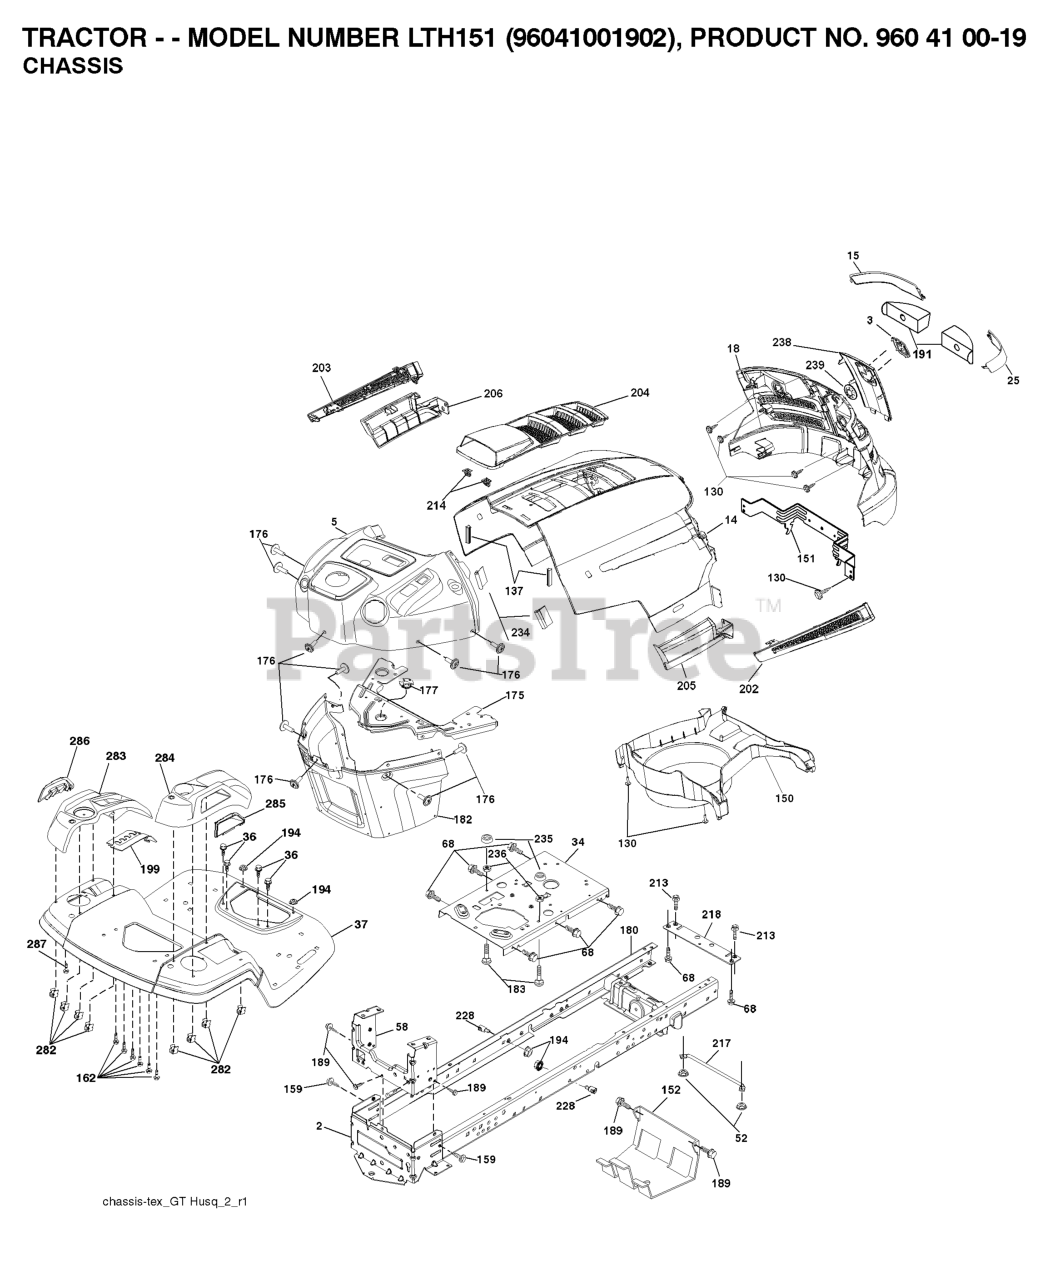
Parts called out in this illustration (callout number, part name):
2	DRAWBAR.LOWER.2PC.18/22
3	RP LOGO
5	DASH
14	HOOD
15	LENS.HUSQVARNA LT.LH
18	RP GRILLE/LENS ASM.
25	LENS.HUSQVARNA LT.RH
34	PLATE.ENGINE.WELDED.CHASSIS
36	SCREW 5/16"
37	RP FENDER.TLT.FS.W/CPH.422
52	LOCKNUT
58	DRAWBAR UPPER 2PC SMALL FENDER
68	Screw 5/16-18 x 1/2 Hex, Self Tapping 5/16-18 x 1/2
130	SCREW
137	BUMPER DASH
151	BRACKET PIVOT
152	SHIELD.BROWNING.W/TEX
159	SCREW, 3/8-16X3/4
162	SCREW.HI-LO.CONSOLE
175	CROSSMEMBER
176	SCREW.#10-24X5/8.RN.QU
177	BUSHING STEERING
180	CHASS.WLDMNT.TL.12GA/2P.48/54
182	DASH LOWER
183	BOLT.5/16-18X1-1/4 FULL.THREAD
189	SCREW
191	INSERT REFLECTIVE
194	NUT LOCK HEX FLANGE 5/16-18
199	PLATE.DECK.LIFT.HUSQ.LT
202	VENT SIDE HOOD RH
203	VENT SIDE HOOD LH
204	VENT TOP HOOD
205	SKIRT SIDE RH
206	SKIRT SIDE LH
213	BOLT
214	CLIP.RETAINER.TINNER.
217	ROD.PIVOT.HOOD
218	X-PIECE.HOOD.STOP.NON/
228	STUD.FASTNER.W/ANTI-ROTATE
234	BUMPER.HOOD.TEX.HUSQVARNA
235	SPACER FENDER
236	NUT.CENTERLOCK.5/16-
238	TRIM
282	CLIP.RETAINER.CONSOLE.LT.HUSQ
283	CONSOLE.DECK.LIFT.HUSQ.N/FR.GR
284	CONSOLE.SHFT.HYD,HUSQL
285	CONSOLE INSERT RH
286	CONSOLE.INSRT.LH.HUSQ.LT.BLACK
287	SCREW 1/4X20
